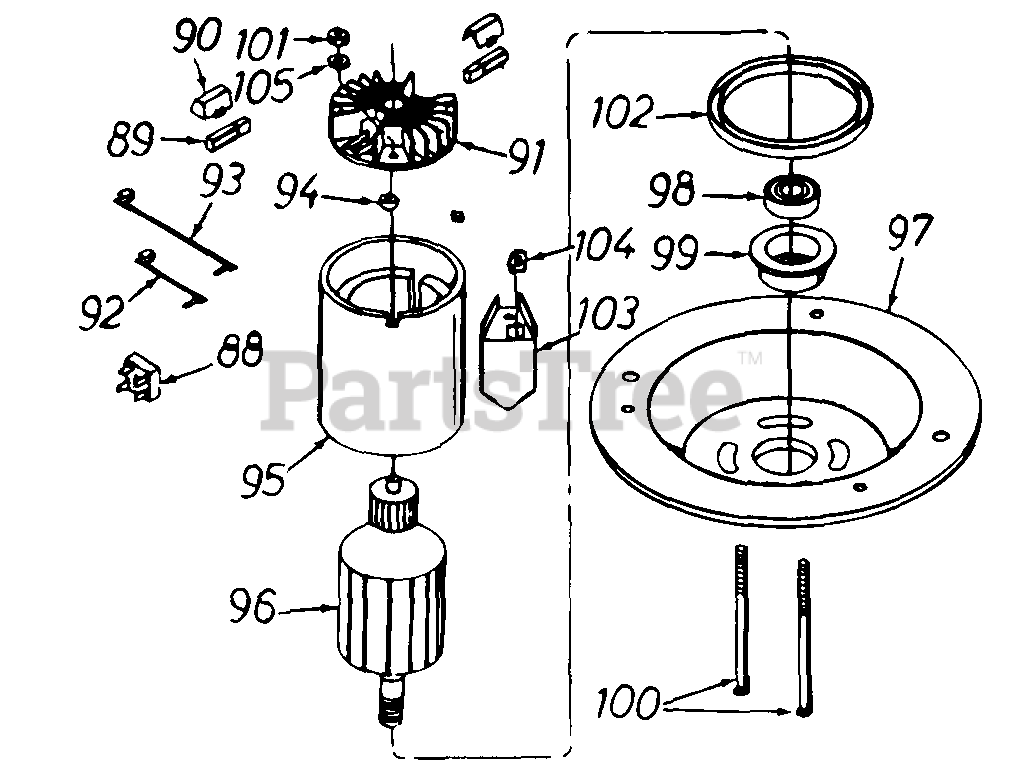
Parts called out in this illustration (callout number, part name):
88	Rectifier
89	Brush and Liner Ass'y.
90	Brush Holder Cap
91	End Shield Brushes
92	Red Brush Lead
93	Blue Brush Lead
94	Needle Bearing
95	Housing Magnet Ass'y.
96	Armature Ass'y.
97	Motor End Plate
98	Ball Bearing
99	Bearing Adapter
100	Carriage Bolt
101	Hex L-Nut 1/4-20 Thd.
102	Motor Hsg. Insulator
103	Cover - Rectifier
104	Strain Relief Bushing
105	Fl-Wash .26" I.D. x .72" O.D.
